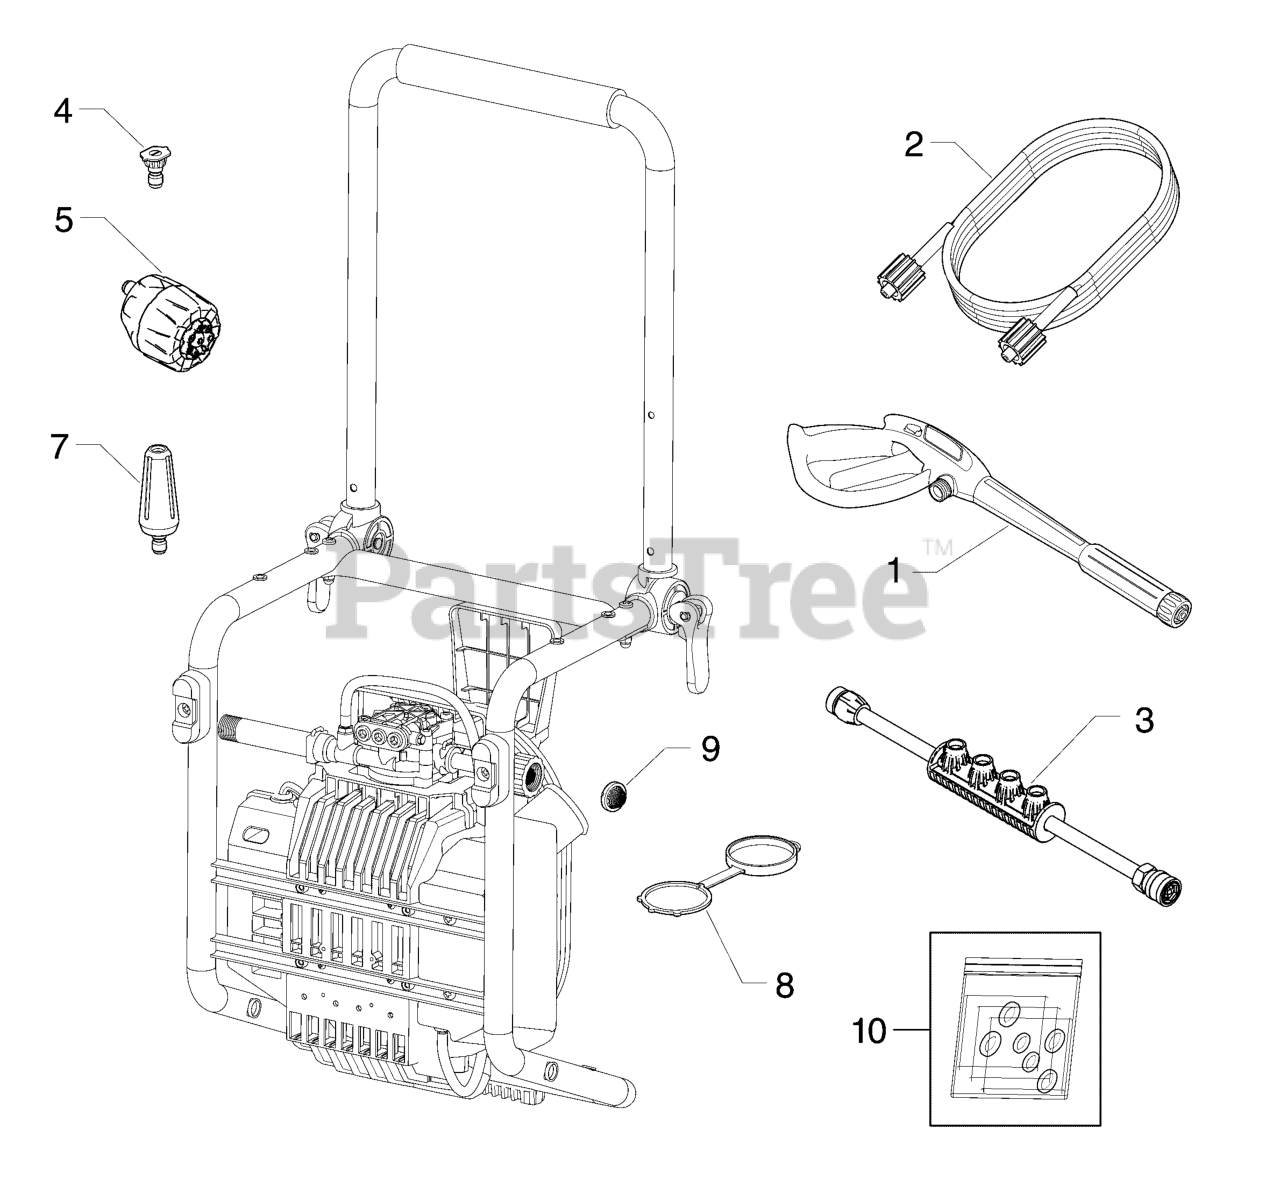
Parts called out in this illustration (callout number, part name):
4	QUICK CONNECT-15
9	FILTER-GARDEN HOSE
10	O-RING, 0.706 ID X 0.097
